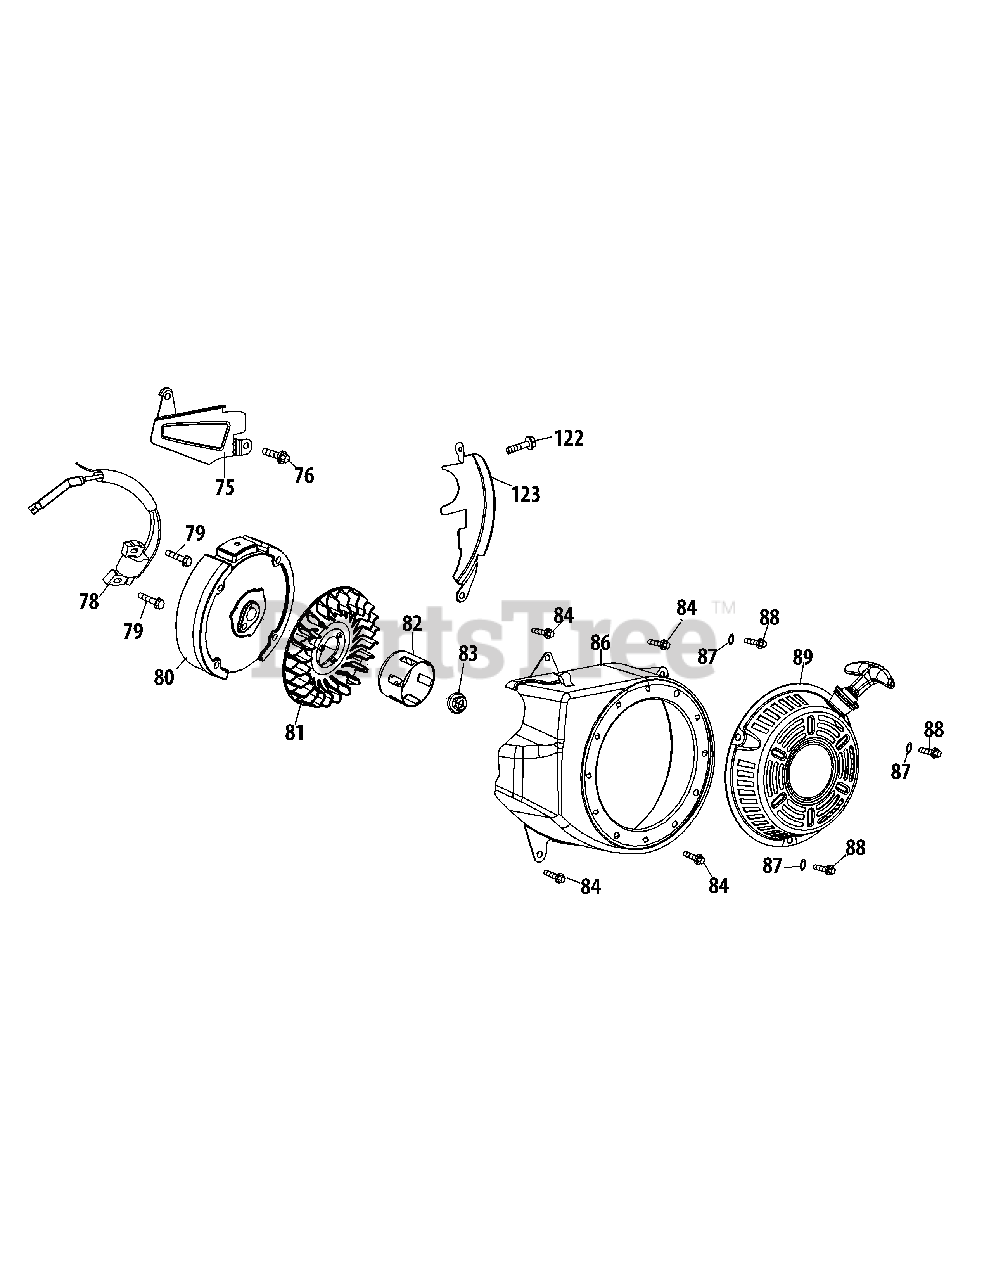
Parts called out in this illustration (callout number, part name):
75	Air Flow Shield
76	Bolt M6×10
78	Ignition Coil Assembly
79	Bolt M6×25
81	Fan, Cooling
82	Pulley, Starter
83	Nut, Special, M14×1.5
84	Bolt M6×12
86	Blower Housing
87	Washer
88	Bolt M6×10
89	Recoil Starter
122	Bolt M6×20
123	Blower Housing Shield
